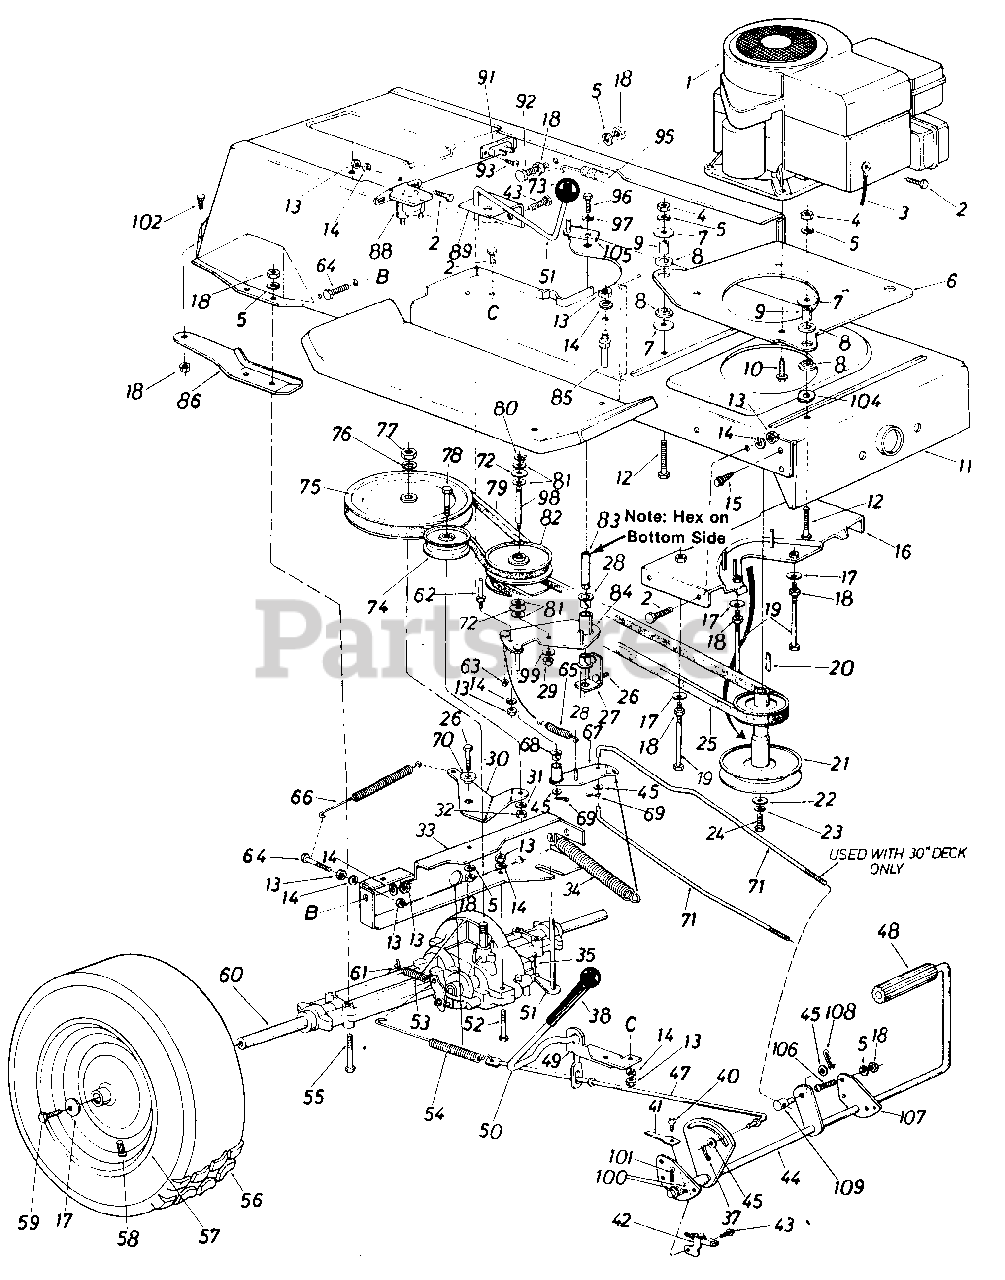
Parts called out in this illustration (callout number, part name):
1	Engine
2	Hex Bolt 1/4-20 x .62" Lg.
3	Electric Ground Wire
4	Hex Nut 5/16-24 Thd.
5	L-Wash. 5/16" I.D.
6	Engine Mounting Plate
7	Fl-Wash. .320" I.D. x 1.25"
8	Engine Mounting Grommet
9	Spacer
10	Hex Bolt 3/8-16 x 1.25" Lg.
11	Lower Frame Ass'y.
12	Hex Bolt 5/16-24 x 1.25"
13	Hex Nut ,, 20 Thd.
14	Wash. 1/4" I.D.
15	l Hex Wash. Hd. AB-Tap Scr. 5/16" x .75" Lg.
16	Belt Guard Brkt. Ass'y.
17	Bell-Wash. .345" I.D. x .88"
18	Hex Nut 5/16-18 Thd.
19	Hex Bolt 5/16-18 x 4.00"
20	Sq. Key 1/4" x 1/4" x 2.00"
21	Engine Pulley 5.56" Dia. & 3.56" Dia.
22	Fl-Wash. 7/16" I.D. x 1.25"
23	L-Wash. 7/16" I.D.
24	Hex Bolt 7/16-20 x 1.50" Lg.
25	Variable-Speed Belt .715 x 53" Lg.
26	Hex Bolt 5/16-18 x .50" Lg.
27	Bearing Shaft Bracket
28	Flanged Nyliner Brg. 518" I.D. x .88" Lg.
29	Hex Nut 3/8-24 Thd.
30	Idler Bracket
31	L-Wash. 3/8" I.D.
32	Hex Nut 3/8-24 Thd.
33	Transaxle Support Brkt.
34	Ext. Spring .94" O.D. x 6.7
35	Cotter Pin 1/8" Dia. x 1.0"
37	Cotter Pin 3/32" Dia. x 1.0"
38	Grip-Black
40	Hex Wash. Hd. Self-Tap Scr. 1/4-20 x .50" Lg.
41	Switch Actuator
42	Safety Switch
43	Hex Wash. Hd. AB-Tap Scr. 1/4 x.62" Lg.
44	Clutch & Brake Pedal Ass'y.
45	Fl-Wash.
47	Brake Rod
48	Foot Pad
49	Brake Lever Bracket
50	Hill Holder Brake Handle
51	Shift Lever Ass'y.
52	Hex Bolt 1/4-28 x 1.75" Lg.
53	Ext. SPring .38" O.D. x 2.5"
54	Ext. Spring .59" O.D. x 7.08"
55	Hex Bolt 5/16-18 x 2.50"
56	Wheel Ass'y. Comp.
57	Wheel Rim Only
58	Air Valve
59	Hex Bolt 5/16-24 x .75" Lg.
60	Transaxle Complete
61	Brake Return Spring Anchor
62	Belt Guard Pin 1/4-20 Thd.
63	Cap Speed Nut 1/4" Dia.
64	Hex Bolt 1/4-20 x .62" Lg. Grade 5
65	Ext. Spring .50" Dia.
66	Ext. Spring .56" O.D. x 5.96"
67	Variable Speed Torque Brkt. Ass'y.
68	Flanged Bearing
69	Cotter Pin 3132" Dia.
70	Shoulder Spacer .500" Dia. x.27" Lg.
71	Speed Control Link
72	Truss Bearing .56 Dia. x 1 .25"
73	Ball Knob
74	Fl-Idler Pulley 3.25" x 1.0"
75	1/2" "V"-Pulley 8" O.D. x .5" I.D.
76	L-Wash. 1/2" I.D.
77	Hex Jam Nut 1/2-20 Thd.
78	Hex Bolt 3/8-24 x 1.50" Lg.
79	Variable Speed Belt .715 x 44" Lg.
80	Snap Ring .56" Dia.
81	Fl-Wash.
82	Variable Speed Pulley Ass'y. 5" O.D.
83	Bearing Shaft
84	Variable Speed Brkt. Ass'y.
85	Belt Guard Pin 1/4" Dia. x 1.68" Lg.
86	Transaxle Support Brkt.-R.H.
88	Solenoid
89	Shift Lever Bracket
91	Circuit Breaker
92	Hex Bolt 5/16-18 x 1.25" Lg.
93	Truss Hd. Phil. Scr. #10 x 1/2" Lg.
95	Ext. Spring .99" O.D. x 11.0"
96	Hex Bolt 3/8-24 x .75" Lg.
97	Bell-Wash. .38" I.D. x .88"
98	Shaft .56" Dia. x 3.875" Lg.
99	Bell-Wash. .39" I.D. x 1.12n
100	Fl-Wash.
101	Cotter Pin
102	Hex Wash. Hd. Scr. 5/16-18 x.62" Lg.
104	Fl-Wash. .32" I.D. x 1.25"
105	Belt Guard
106	Truss Mach. Scr. 5/16-18 x .75" Lg.
107	Pedal Bracket
108	Hairpin Cotter 1/8" Dia.
109	Ferrule
